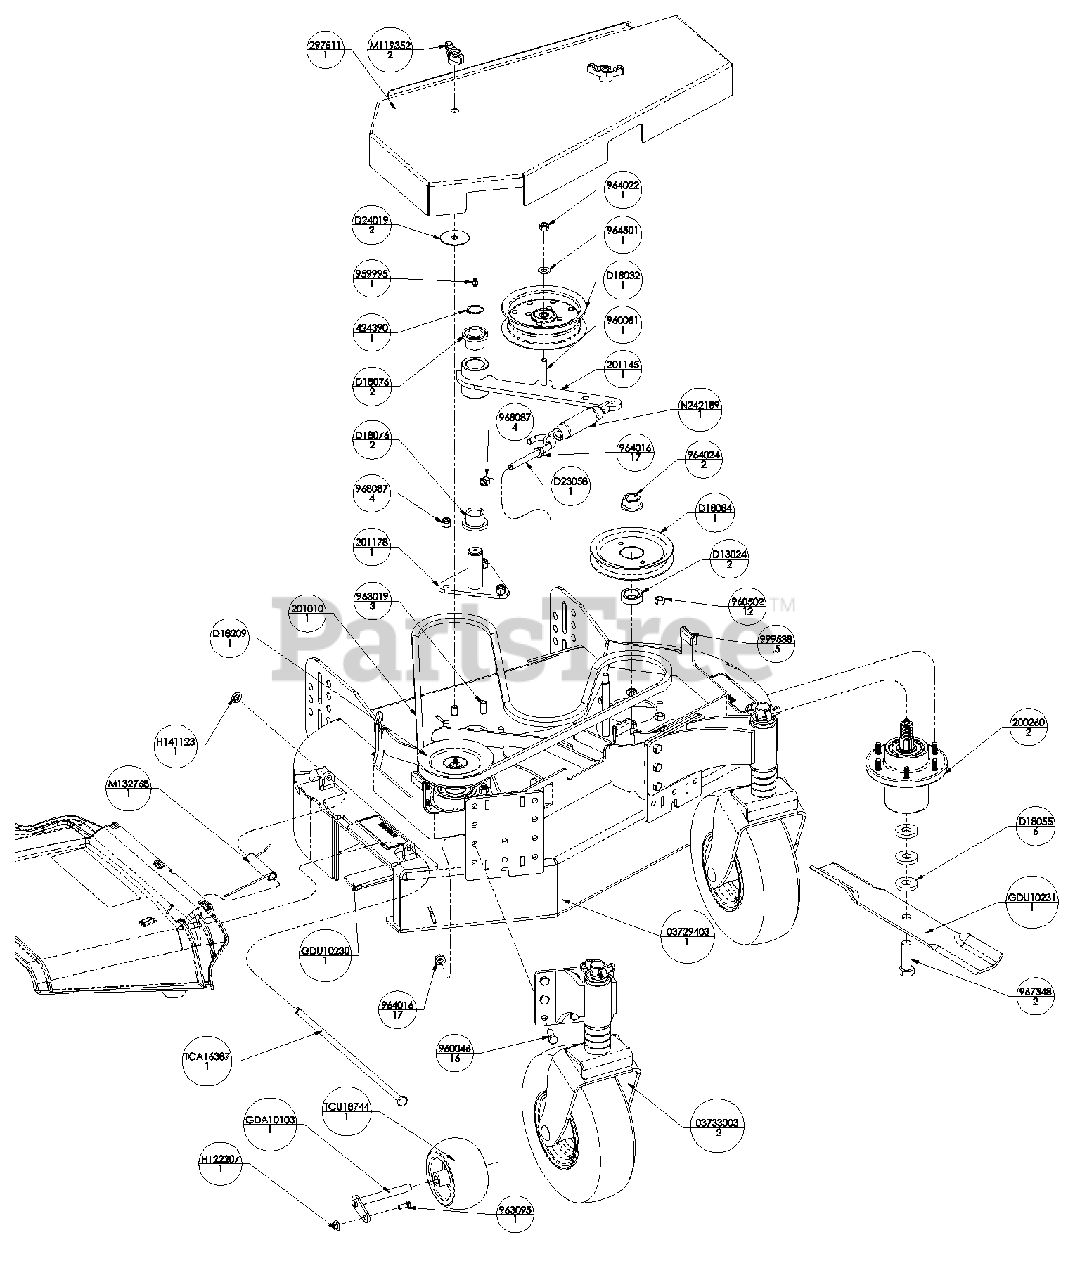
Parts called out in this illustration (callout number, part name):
1	SPACER, 1.500X1.000X.510 Y
2	PULLEY, FLAT 5.0X.38 W/BRG
3	WASHER, BLADE
4	BRG, FLG 1.00X1.25X1.00
5	PULLEY, SPLINE SPINDLE OFFSET
6	PULLEY, V-BELT 5.27X.990 W/SPL
7	WASHER, .402X2.00X.055 FEND Y
8	J-BOLT, 3/8-16 X 4.00 Y
9	PIVOT, RETAINER WELD
10	BLADE, 16.50 LO-LIFT
11	BLADE, 18"
12	NUT-1/4" FLANGE PREVAILING TOR
13	RETAINER #
14	SPRING,CHUTE GUARD
15	KNOB, LOCKING
16	SPRING, TENSION
17	CHUTE DISCHARGE ASST #
18	WHEEL, GAGE
19	ASSY, SPINDLE HOUSING
20	BELT, HB 80.3 EL AMD OHR
21	WLDT, IDLER ARM
22	WLDT, 34" DECK
23	ASSY, FR WHEEL CASTER
24	SHIELD, DECK 34
25	WLDT, IDLER PIVOT
26	SNAP RING, 1.00 X .042 EXT
27	FTG, 1/4-28 STRGT GREASE ZERK
28	BOLT, 3/8-16 X 1.00 HEX 5 Y
29	BOLT, 3/8-16 X 2.25 HEX 5 Y
30	NUT, 3/8-16 STD HEX GR5 Y
31	BOLT, 3/8-16 X 1.00 CRG 5 SN Y
32	BOLT, 1/4-20 X .750 CRG 5 Y
33	LOCKNUT, 3/8-16 WHIZ Y
34	LOCKNUT, 3/8-16 CROWN Y
35	WASHER, .406 X .813 X .065 FLAT Y
36	LOCKNUT, 3/4-16 CROWN Y
37	BOLT, 5/8-11 X 2.00 HEX 8 Y
38	LOCKNUT, 3/8-16 NYLOC Y
39	TRIM 1/4
